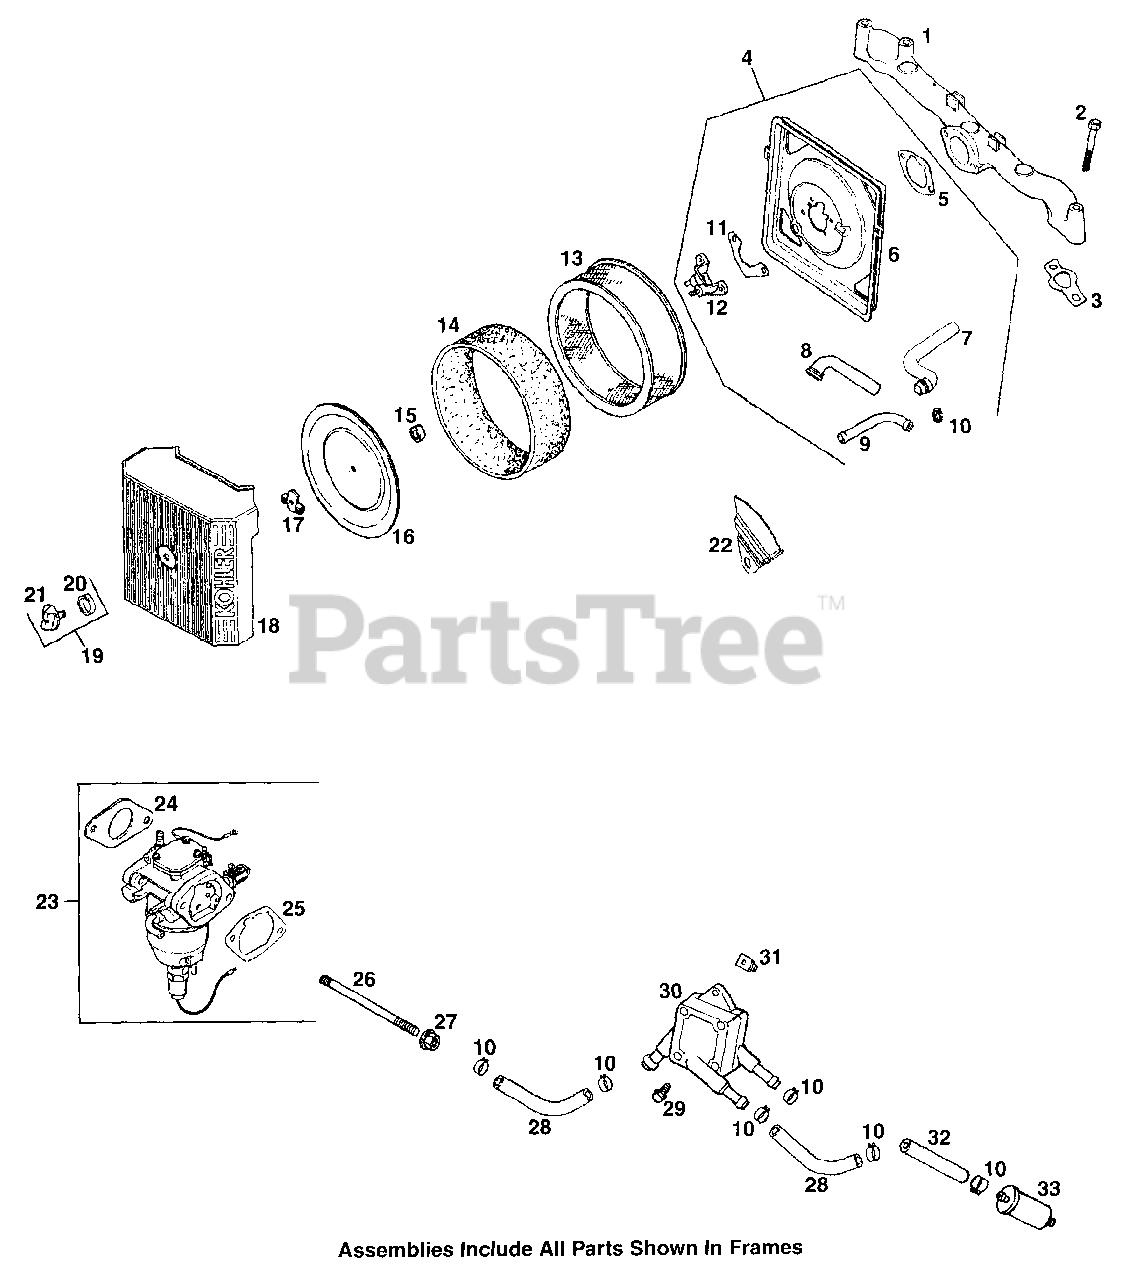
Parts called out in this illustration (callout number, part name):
1	Intake Manifold
2	Hex Flange Screw, M6 x 1.0 x 55
3	Intake Manifold Gasket
4	Air Cleaner Base Kit
5	Air Cleaner Base Gasket
6	Air Cleaner Base
7	Breather Hose
9	Breather Hose
10	Hose Clamp
11	Fuel Spit-Back Cup Gasket
12	Spit-Back Cup w/ Stud
13	Air Cleaner Element
14	Pre Cleaner
15	Inner Air Cleaner Seal
16	Inner Air Cleaner Cover
18	Air Cleaner Cover
19	Knob Kit w/ Seal
22	Spit-Back Cup Baffle
23	Carburetor Kit w/ Gaskets
24	Carburetor Gasket
25	Air Cleaner Base Gasket
26	Stud, M6 x.8 x 95
27	Hex Flange Nut, M6 x .8
28	Fuel Line, 10-5/8"
29	Hex Cap Screw, M6 x 1.7 x 18
31	Plastic Nut
32	Fuel Line, 3 1/2"
33	Fuel Filter
